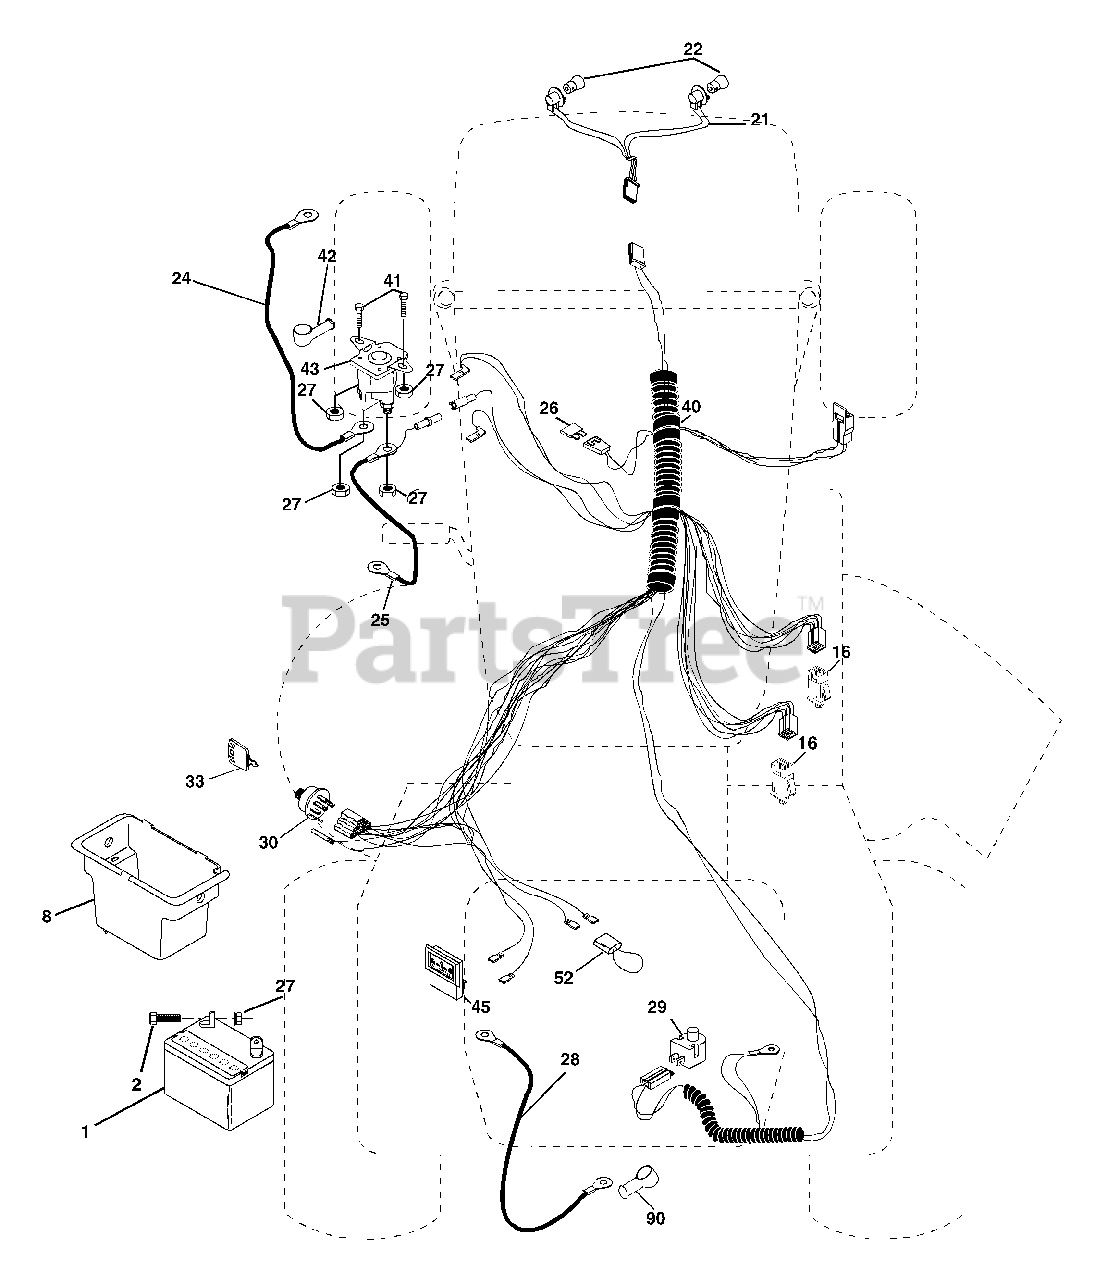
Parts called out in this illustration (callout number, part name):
1	Battery 12 Volt 25 Amp
2	Bolt Hex Hd 1/4-20 unc x 3/4
8	Box Battery
16	Switch Interlock Push -In
21	Harness Asm Light W/4152J
22	Bulb Light #1156
24	Cable Battery 6 Ga. 11"red
25	Cable Battery 6 Ga. w/16 wire,red
26	Fuse 20 AMP
27	Nut Keps Hex 1/4-20 unc
28	Cable Ground 6 Ga. 12" black
29	Switch Plunger Nc Gray
30	Switch Ign
33	Key Ign
40	Harness Ign
41	Bolt Blk Fin Hex 1/4-20 x 1/2
42	Cover Terminal Red
43	Solenoid
45	Ammeter
52	Protection Wire Loop
90	Cover Terminal
